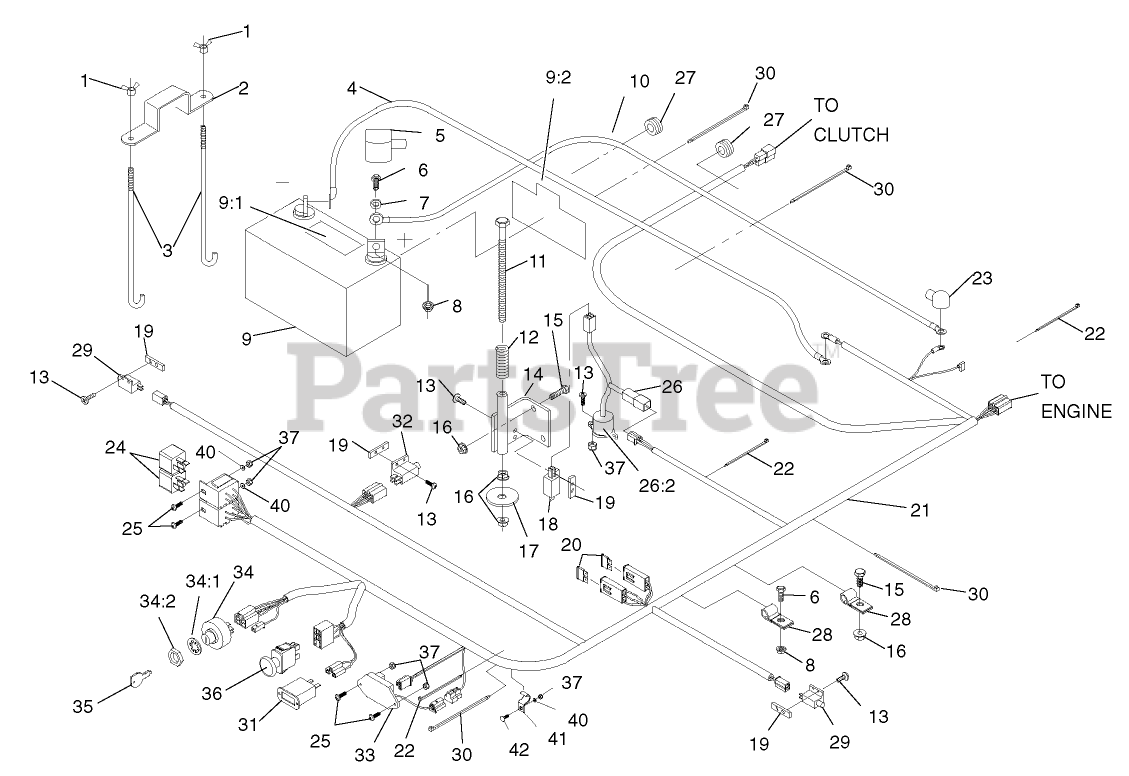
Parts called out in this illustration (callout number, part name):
1	WINGNUT
2	STRAP-HOLDDOWN
3	BOLT-HOLDDOWN
4	CABLE-GROUND, NEGATIVE
5	INSULATOR-BATTERY
6	SCREW-HH
7	WASHER-FLAT
8	NUT-HF
9	BATTERY
9:1	Decal-Battery
9:2	Decal-Battery
10	WIRE-STARTER
11	SCREW-HH
12	SPRING-SWITCH, SEAT
13	SCREW-PPH
14	BRACKET-SWITCH, SEAT
15	SCREW-HH
16	NUT-HF
17	WASHER
18	SWITCH-CLOSED, NORMALLY
19	PLATE-TAPPED
20	FUSE-BLADE TYPE, 20 AMP
21	HARNESS-WIRE
22	TIE-CABLE
23	INSULATOR-SOLENOID
25	BOLT-CARR
26	TILT SWITCH ASM
26:2	DECAL-SWITCH, MERCURY
27	GROMMET
28	CLIP-LOOM
29	SWITCH-OPEN, NORMALLY
30	TIE-PLASTIC
31	METER-HOUR
32	SWITCH
33	MODULE-DELAY, SEAT
34	Key Switch ASM
34:1	WASHER-TOOTH, INTERNAL
34:2	NUT-HH
35	KEY-IGNITION
36	SWITCH-DELTA
37	NUT-LOCK, NI
40	WASHER-FLAT
41	CLIP-HALF, LOOM
42	BOLT-CARR
